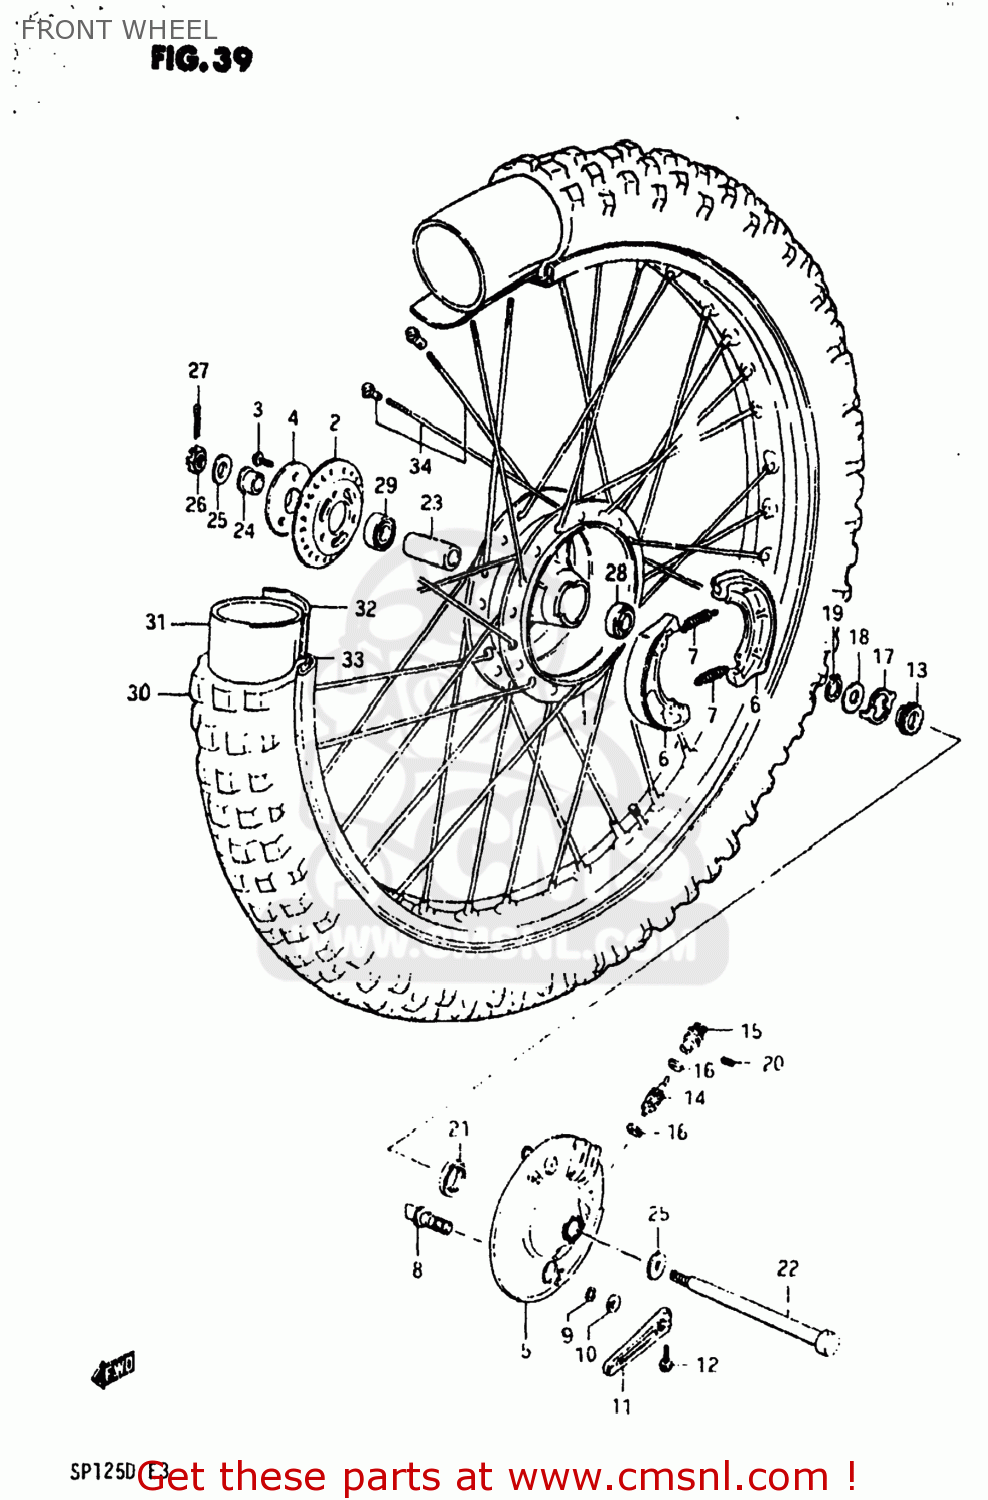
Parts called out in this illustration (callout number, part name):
1	HUB,FR WHEEL
2	FLANGE,FR HUB,R
3	BOLT
4	PLATE,FRONT HUB BEARING
5	PANEL,FRONT HUB
6	SHOE,BRAKE
7	SPRING(L:34)
8	CAM,FRONT BRAKE
9	O-RING (D:2.4 ID:13.8)
10	WASHER (14.5X22X1.6)
11	LEVER,FRONT BRAKE CAM
12	BOLT
13	GEAR,SPEEDOMETER
14	PINION,SPEEDOMETER
15	BUSH,METER GEAR OUTER
16	WASHER (5.1X9X0.4)
17	DRIVER,SPEEDOMETER GEAR
18	WASHER(18.5X24X1)
19	CIRCLIP
20	SCREW
21	OIL SEAL (43X58X7)
22	AXLE,FRONT
23	SPACER (12.6X19X52)
24	SPACER,FR AXLE,R
25	WASHER
26	NUT 12MM
27	COTTER PIN
28	BEARING
29	BEARING, RH
30	TIRE,FRONT
31	TUBE
32	PROTECTOR,WHEEL,INNER
33	RIM,FR WHEEL(1.60X21)
34	SPOKE ASSY,FR WHEEL
